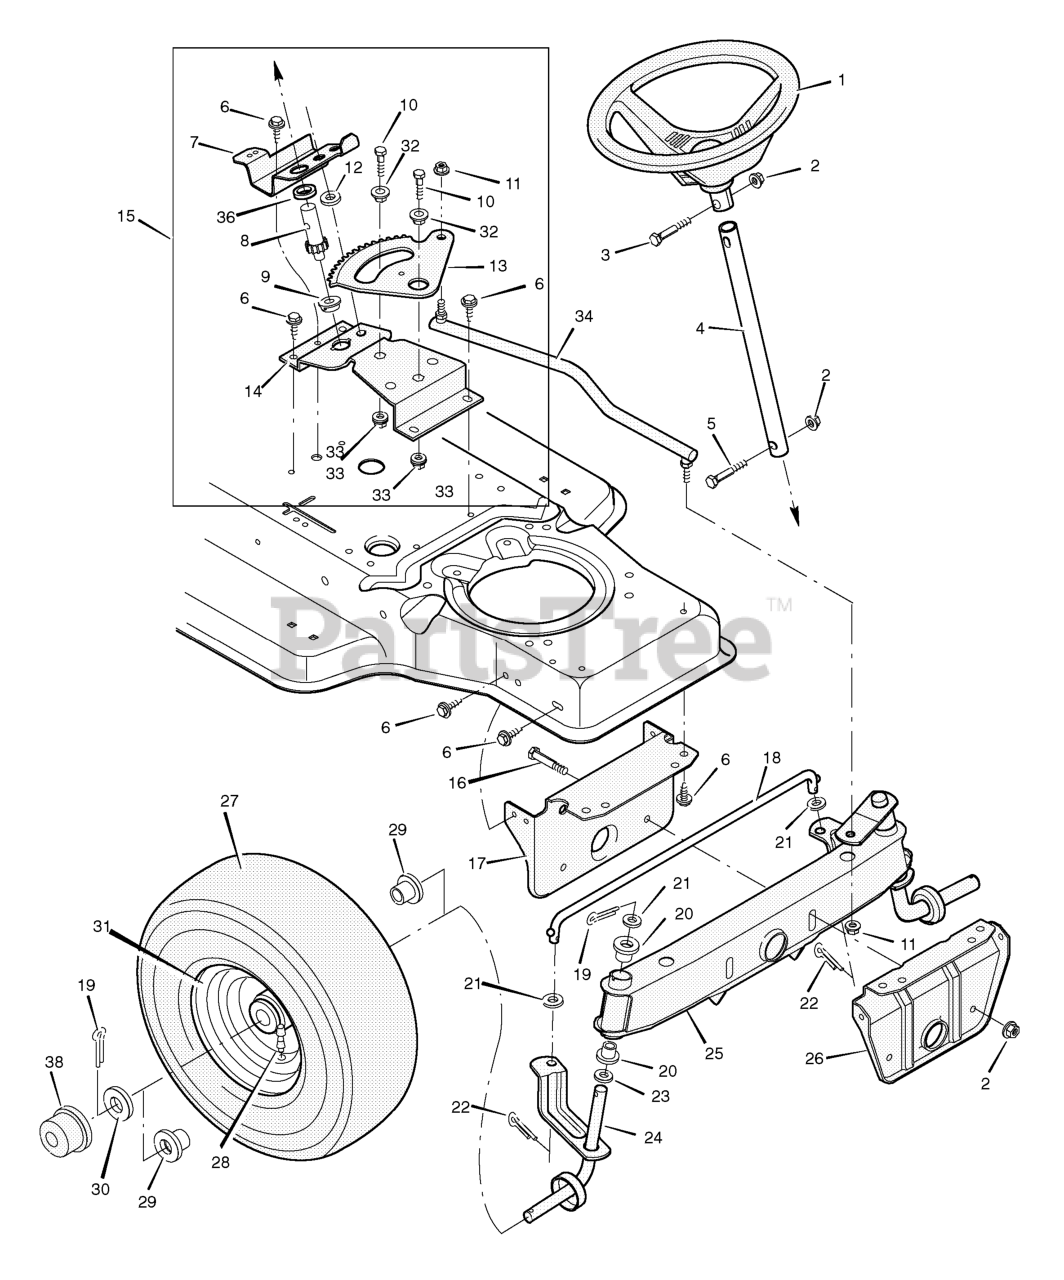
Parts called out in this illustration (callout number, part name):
1	Wheel, Steering
2	Nut, Hex
3	Bolt, Hex
4	Post, Steering
5	Bolt, Hex
7	Bracket, Sector
8	Gear, Pinion
9	Bearing
10	CAPSCREW, Hex Head, 5/16-18 x 1
11	Locknut, Flange
13	Gear, Sector
14	Bracket, Sector
15	Kit, Steering Gear
16	Bolt, Hex
17	Support, Rear Axle
18	Rod, Tie
19	Pin, Cotter
20	Bearing
22	Pin, Cotter
24	Spindle Assembly, Right
25	Spindle Assembly, Axle & Left
26	Support, Front Axle
28	Stem, Valve
29	Bearing, Wheel
31	Wheel & Tire Assembly
32	Bearing
33	Locknut, Flange
34	Link, Drag
36	Spacer, Pinion Gear
38	Hub Cap
